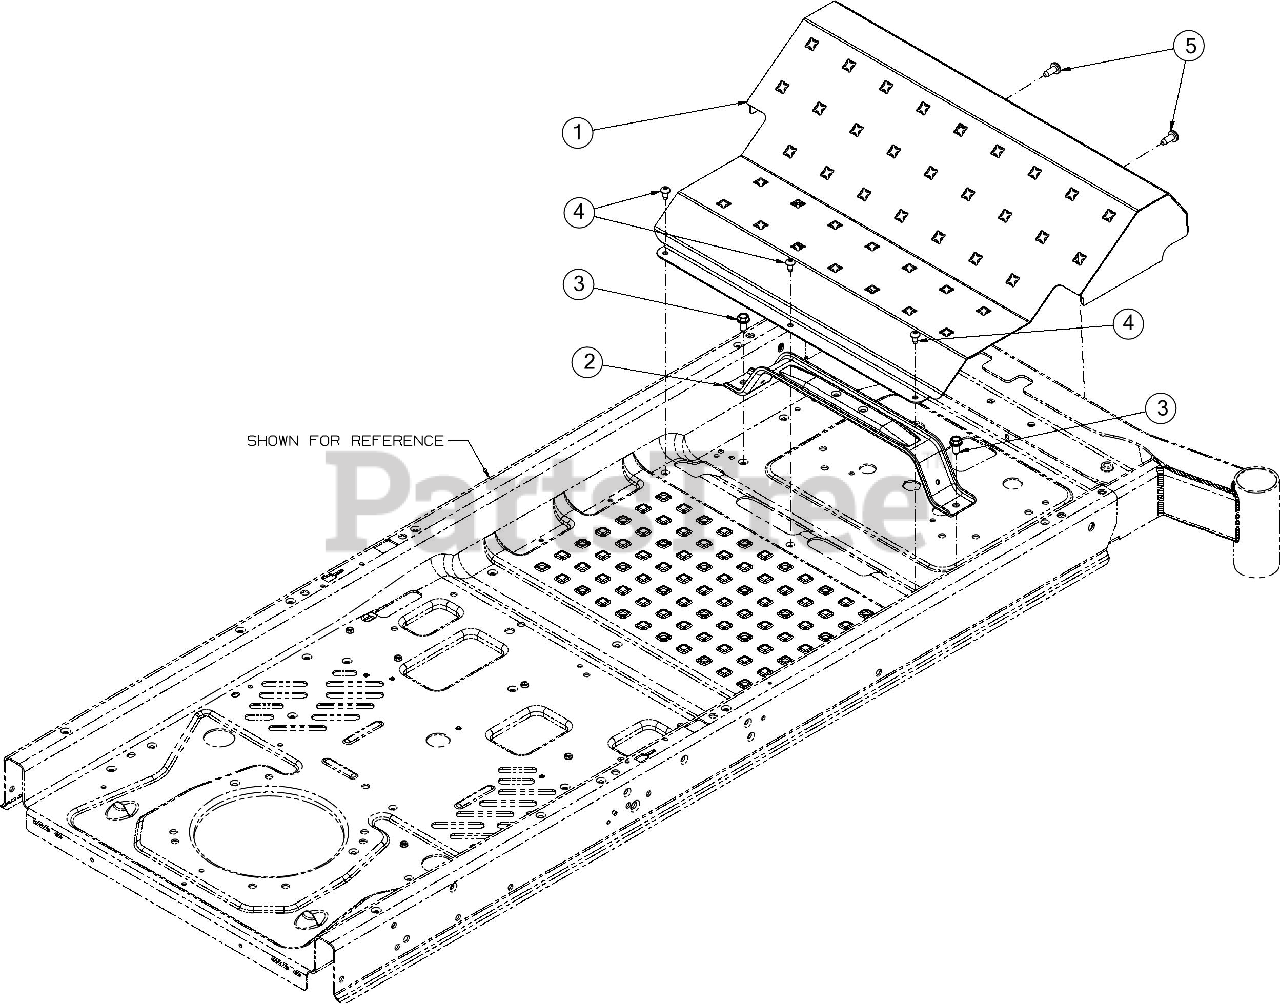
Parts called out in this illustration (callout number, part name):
1	FLOORBOARD
2	STEERING SUPPORT BRACKET
3	SCREW 5/16-18 x .750
4	SCREW 1/4-20 x .5
5	SCREW 5/16-18 X.75
